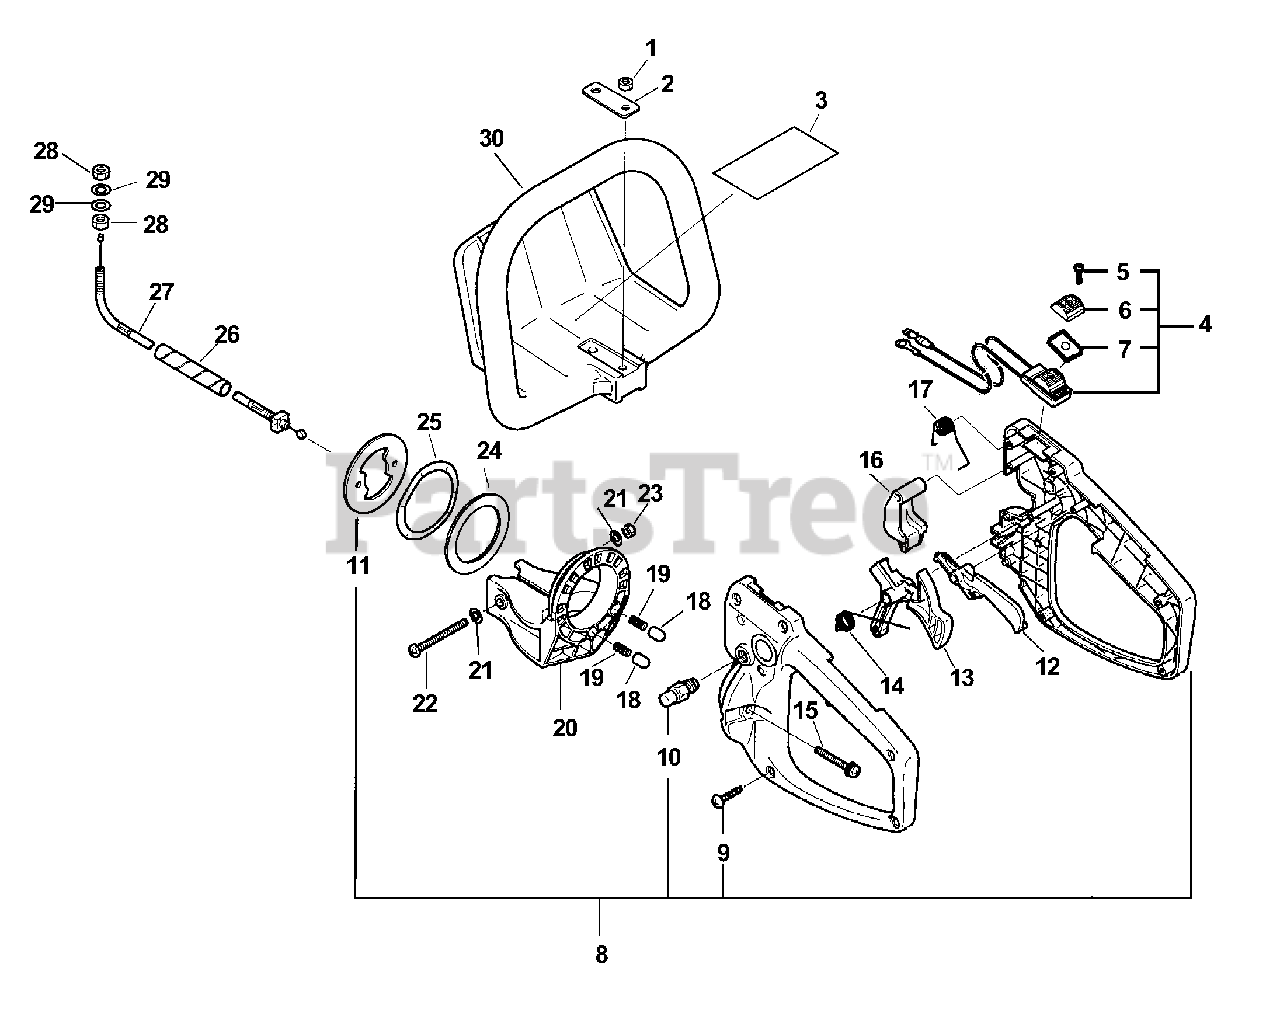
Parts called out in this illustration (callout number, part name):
1	NUT, LOCK M5
2	PLATE, EYE
3	LABEL, CAUTION
3	LABEL - CAUTION
4	SWITCH, ON-OFF
5	SCREW 3×10
6	KNOB, SWITCH - ORANGE
7	LABEL, SWITCH
8	REAR HANDLE ASSY
9	SCREW 4×16
10	LOCK, THROTTLE
11	BRACKET, HANDLE
12	LOCKOUT, THROTTLE
13	TRIGGER, THROTTLE
15	SCREW 5×30
17	SPRING, TORSION
18	PIN, CLEVIS
20	BRACKET, HANDLE
21	WASHER 5.5×12×0.8
22	SCREW 5×47
23	NUT, LOCK M5
25	WASHER
27	CABLE, THROTTLE
29	WASHER 6.5×11.5×0.8
30	HANDLE, SUPPORT
